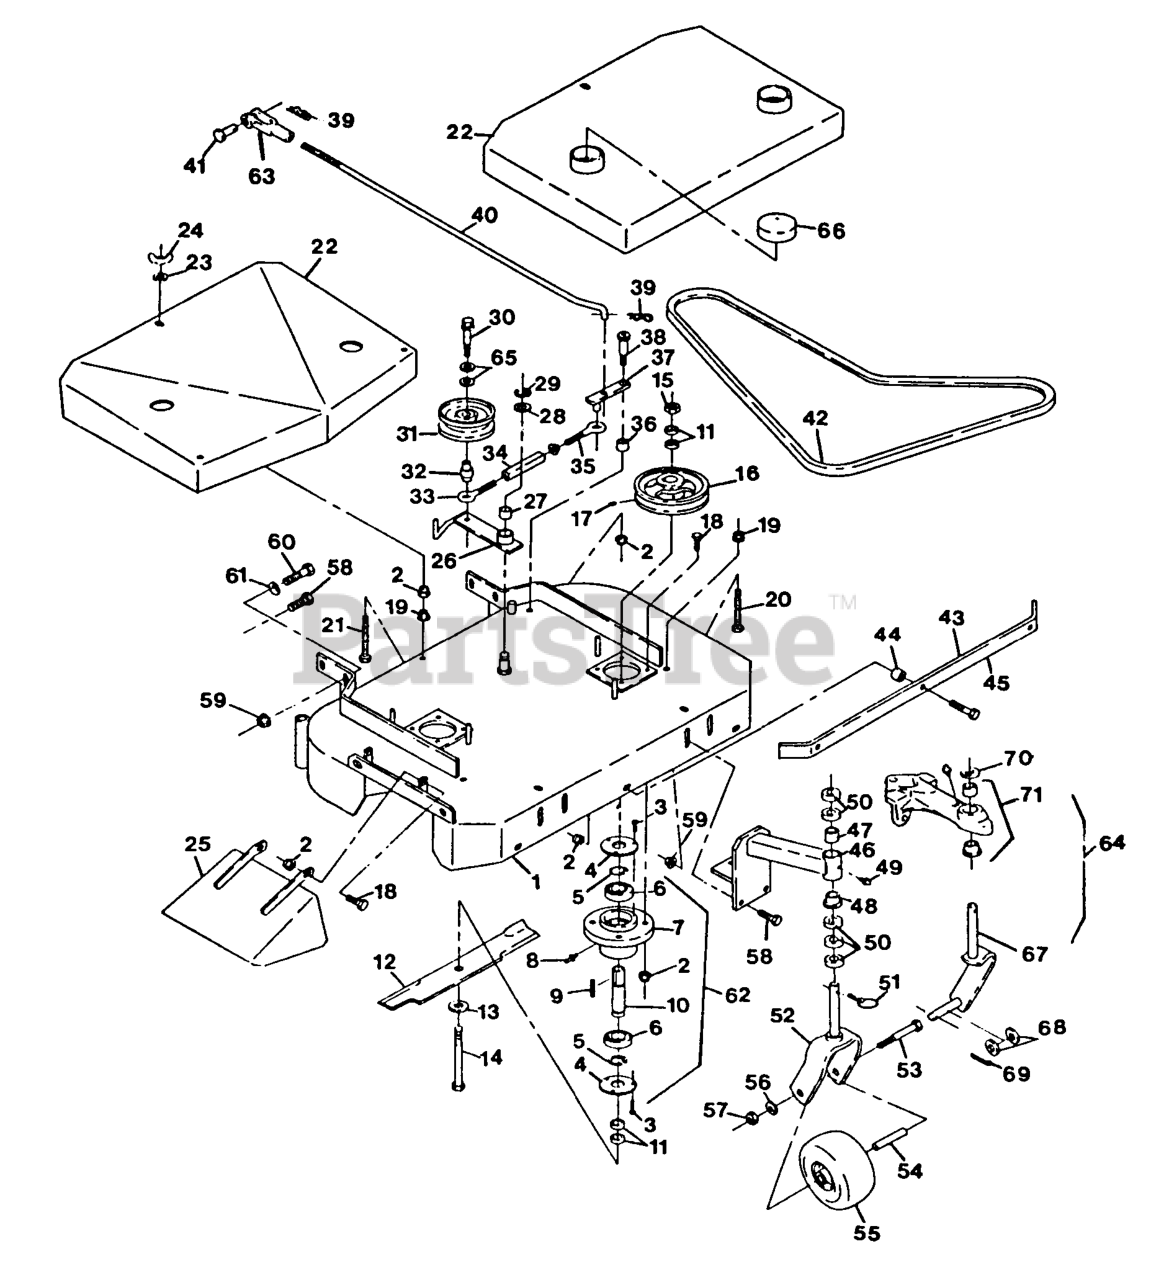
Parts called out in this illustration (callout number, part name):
3	SCRWMACH PHS
7	HOUSING,CUTTER
10	SPINDLE,CUTTER
16	PULLEY,CAST IRON
17	SCREW-SET
20	BOLT,TAP HH
21	BOLTTAP HH
27	BEARING,POWDERED METAL
28	WASHER-SPINDLE
31	IDLER,PULLEY
32	BUSHING-ENGAGEMENT
33	EYEBOLT-THREAD, LH
34	BODY-TURNBUCKLE
35	EYEBOLT-THREAD, RH
38	BOLT,SHLDR KSKH
39	PIN-COTTER
41	PIN-CLEVIS
42	BELT,BLADE DRIVE
47	BEARING,STRAIGHT
50	SPACER-CASTER
62	HOUSING,CUTTER COMPLETE
63	YOKE-ADJUSTABLE
66	CAP,SPINDLE GUARD
67	WLD,STRUT CASTER
